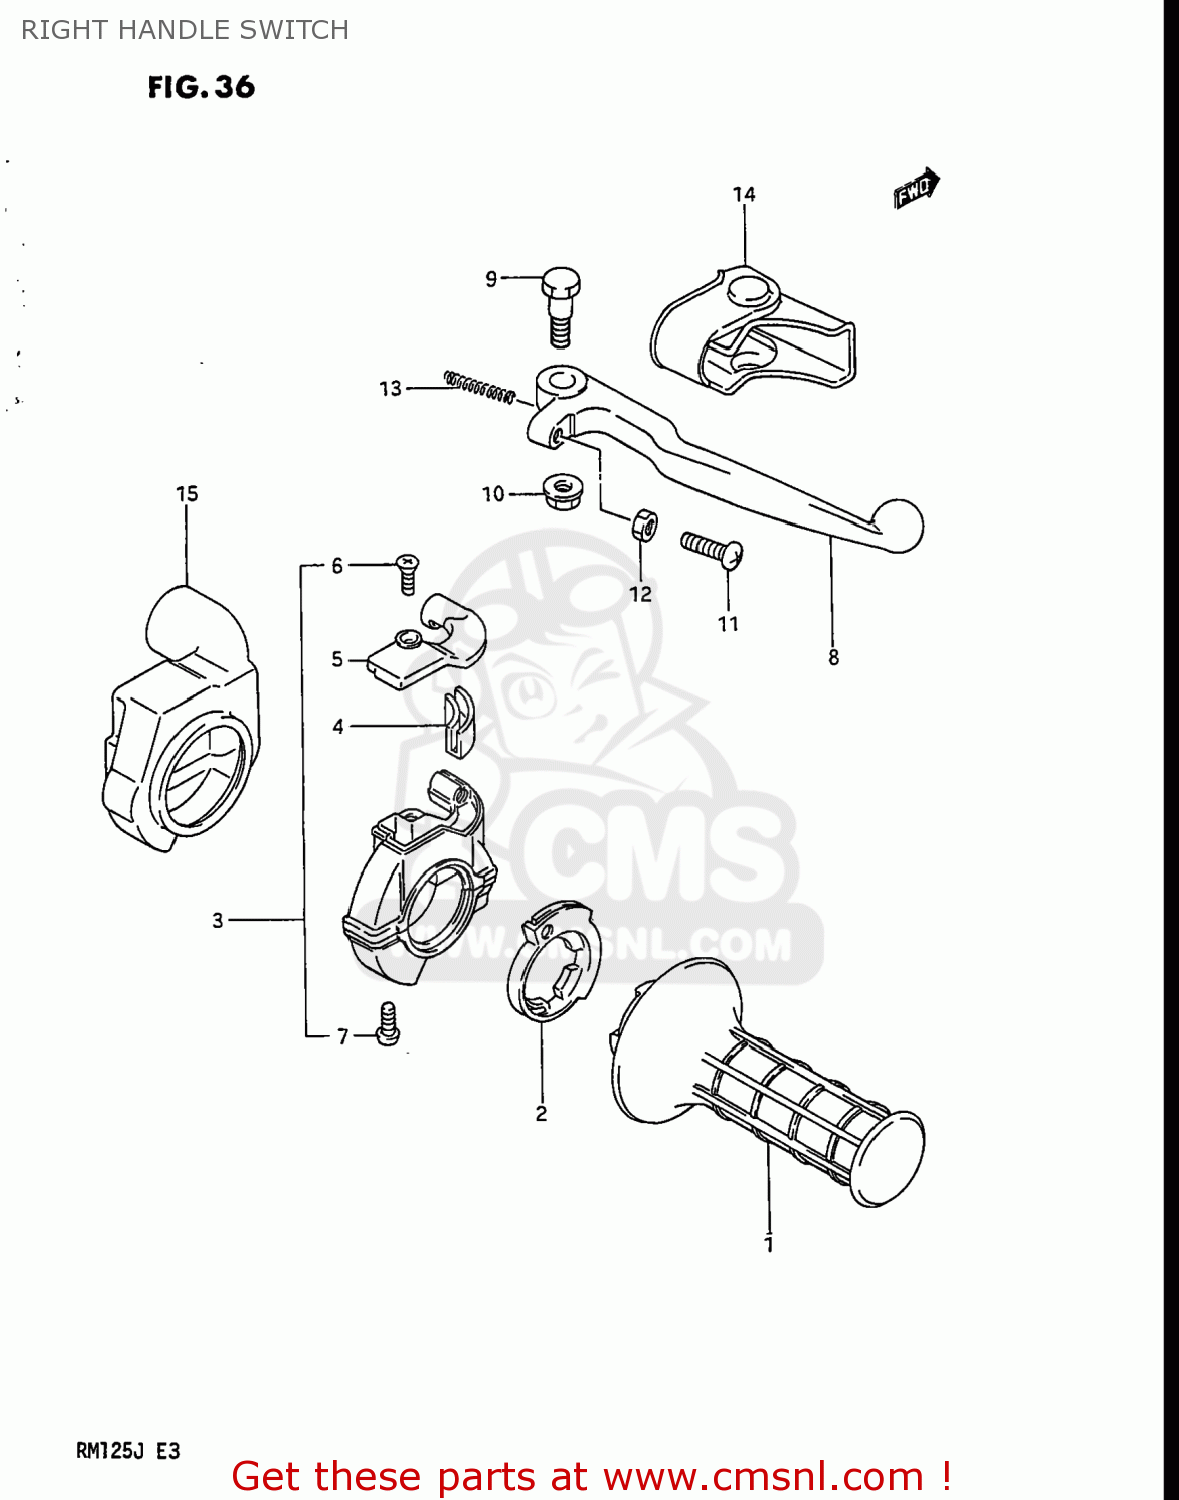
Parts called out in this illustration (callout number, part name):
1	GRIP,THROTTLE
2	ROTOR,THROTTLE GRIP
3	CASE ASSY,THROTTLE
4	GUIDE PIECE,THROTTLE
5	COVER,THROTTLE CASE
6	SCREW
7	SCREW
8	LEVER,BRAKE
9	BOLT,BRAKE LEVER
10	NUT,BRAKE LEVER
11	BOLT,ADJUST
12	NUT ,5MM
13	SPRING,RETURN
14	COVER,BRAKE LEVER
15	COVER,THROTTLE CASE
